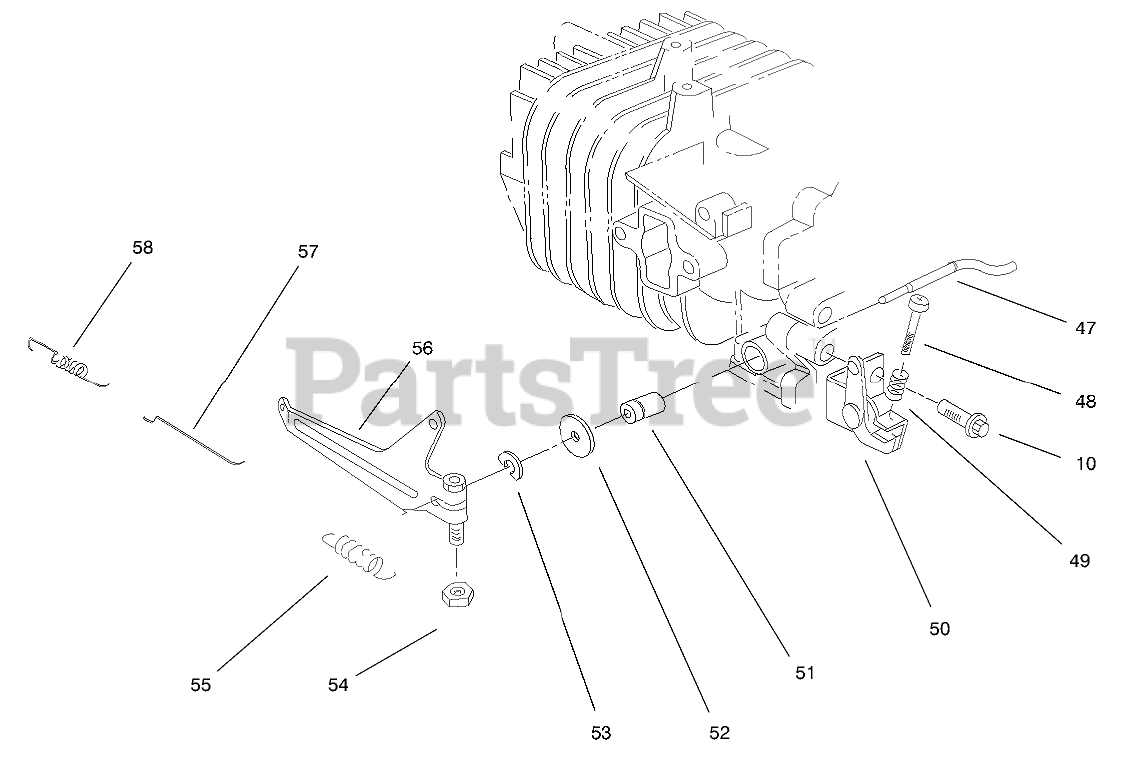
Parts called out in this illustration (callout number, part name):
47	SHAFT
48	SCREW
49	SPRING
50	GOV SPR BRKT
51	SEAL-OIL
52	WASHER
53	E-RING
55	GOV SPRING
56	GOVERNOR ARM
57	CARB ROD
58	CARB SPRING
78	SCREW
79	GASKET
